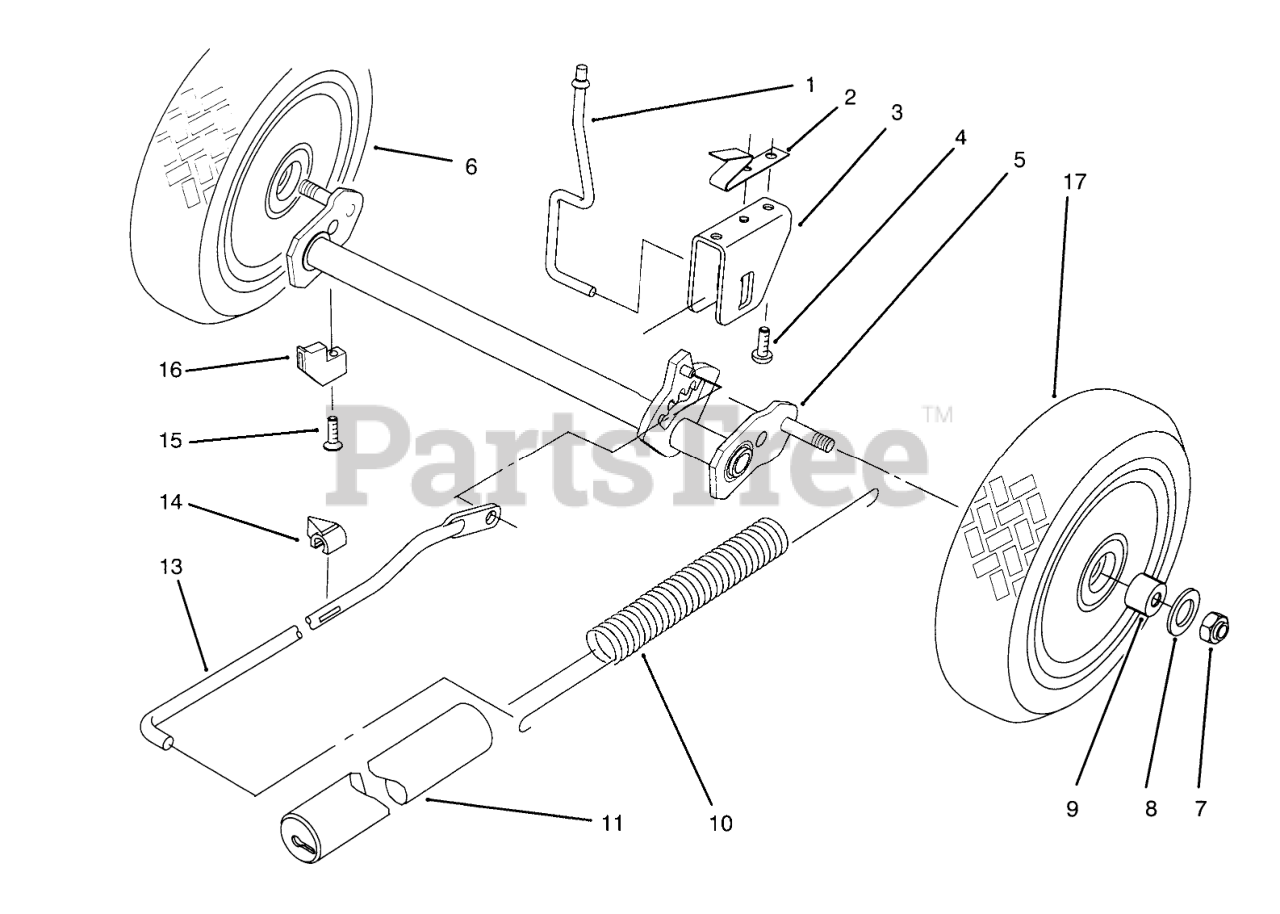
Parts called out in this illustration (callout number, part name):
1	Rod-Trigger
2	SPRING-RETURN, TRIGGER
3	SADDLE-HEIGHT OF CUT
4	SCREW-RH
5	AXLE-REAR
6	WHEEL-REAR
7	NUT-HH
8	WASHER-WHEEL
9	BUSHING
10	SPRING-COUNTERBALANCE
11	COVER-SPRING
13	ROD-LINK
14	INDICATOR-HEIGHT OF CUT
15	SCREW-RETAINER
16	RETAINER - AXLE
17	WHEEL-SMART, REAR
